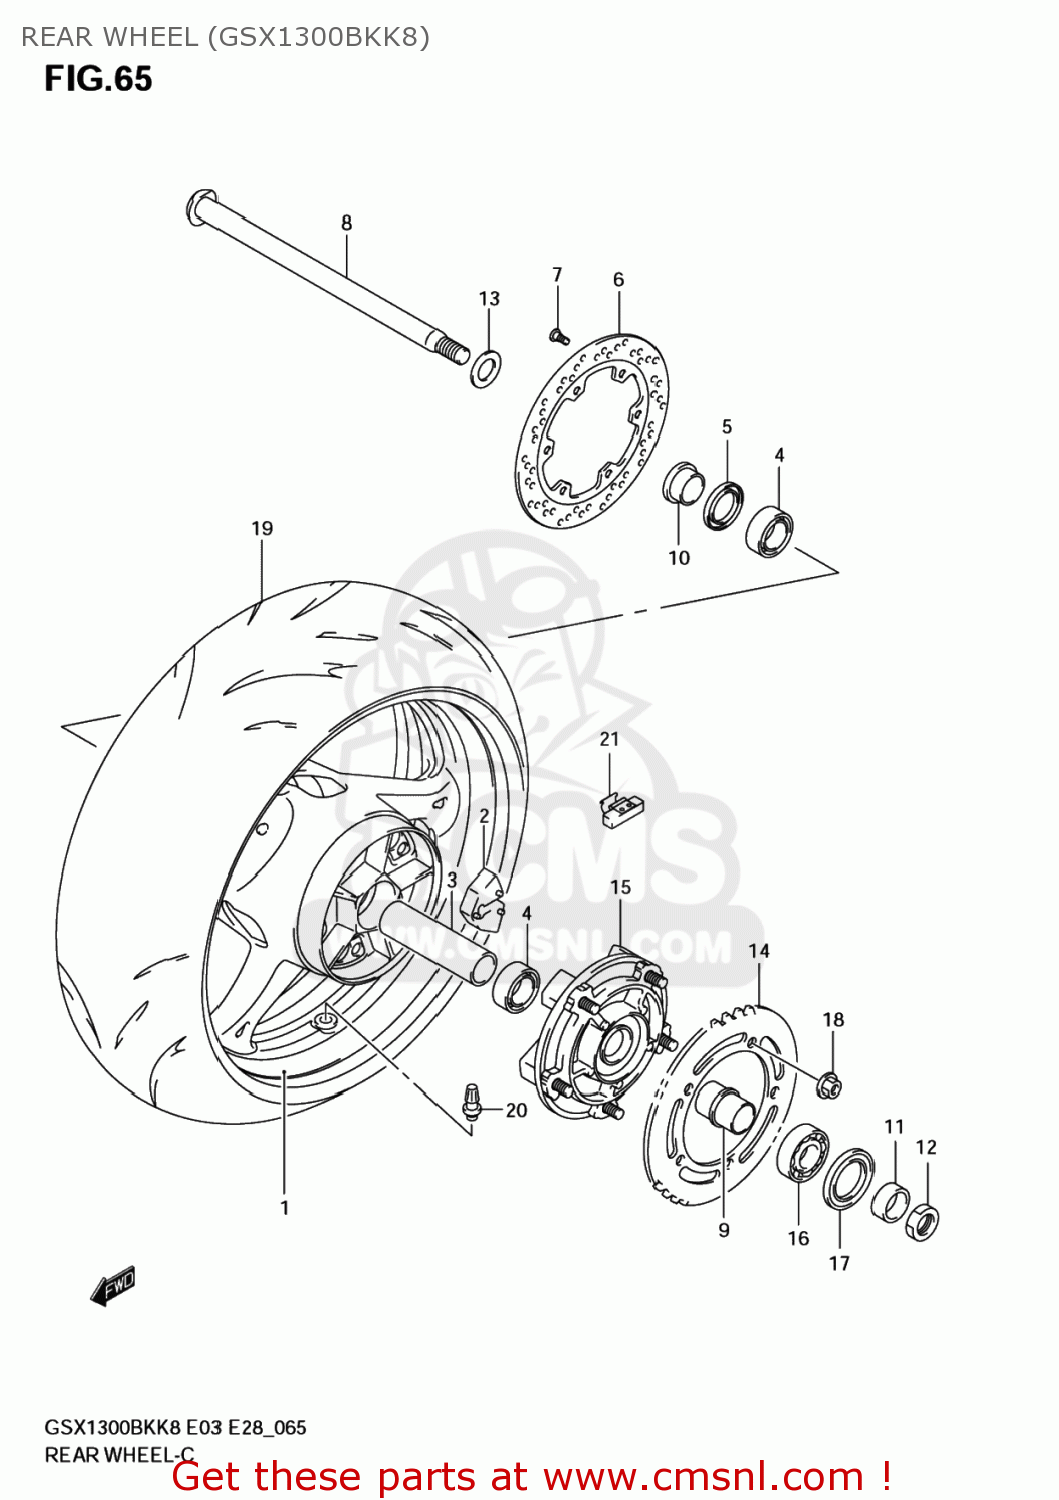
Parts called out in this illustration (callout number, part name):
1	WHEEL,RR(17M/CXMT6.00)
2	ABSORBER,RR HUB SHOCK
3	SPACER,RR WHEEL BEARING
4	BEARING(28X52X12)
5	SEAL,OIL(37X52X8)
6	DISC,RR BRAKE
7	BOLT(8X21)
8	AXLE,RR
9	RETAINER,RR SPROCKET DRUM
10	SPACER,RR AXLE,R
11	SPACER,RR AXLE,L
12	NUT
13	WASHER(25.2X42X3.2)
14	SPROCKET,REAR(
15	DRUM,RR SPROCKET
16	BEARING
17	SEAL,OIL(39X65X7)
18	NUT
19	TIRE,RR
20	VALVE ASSY,WHEEL RIM(TR412)
21	BALANCER,WHEEL(10G)
